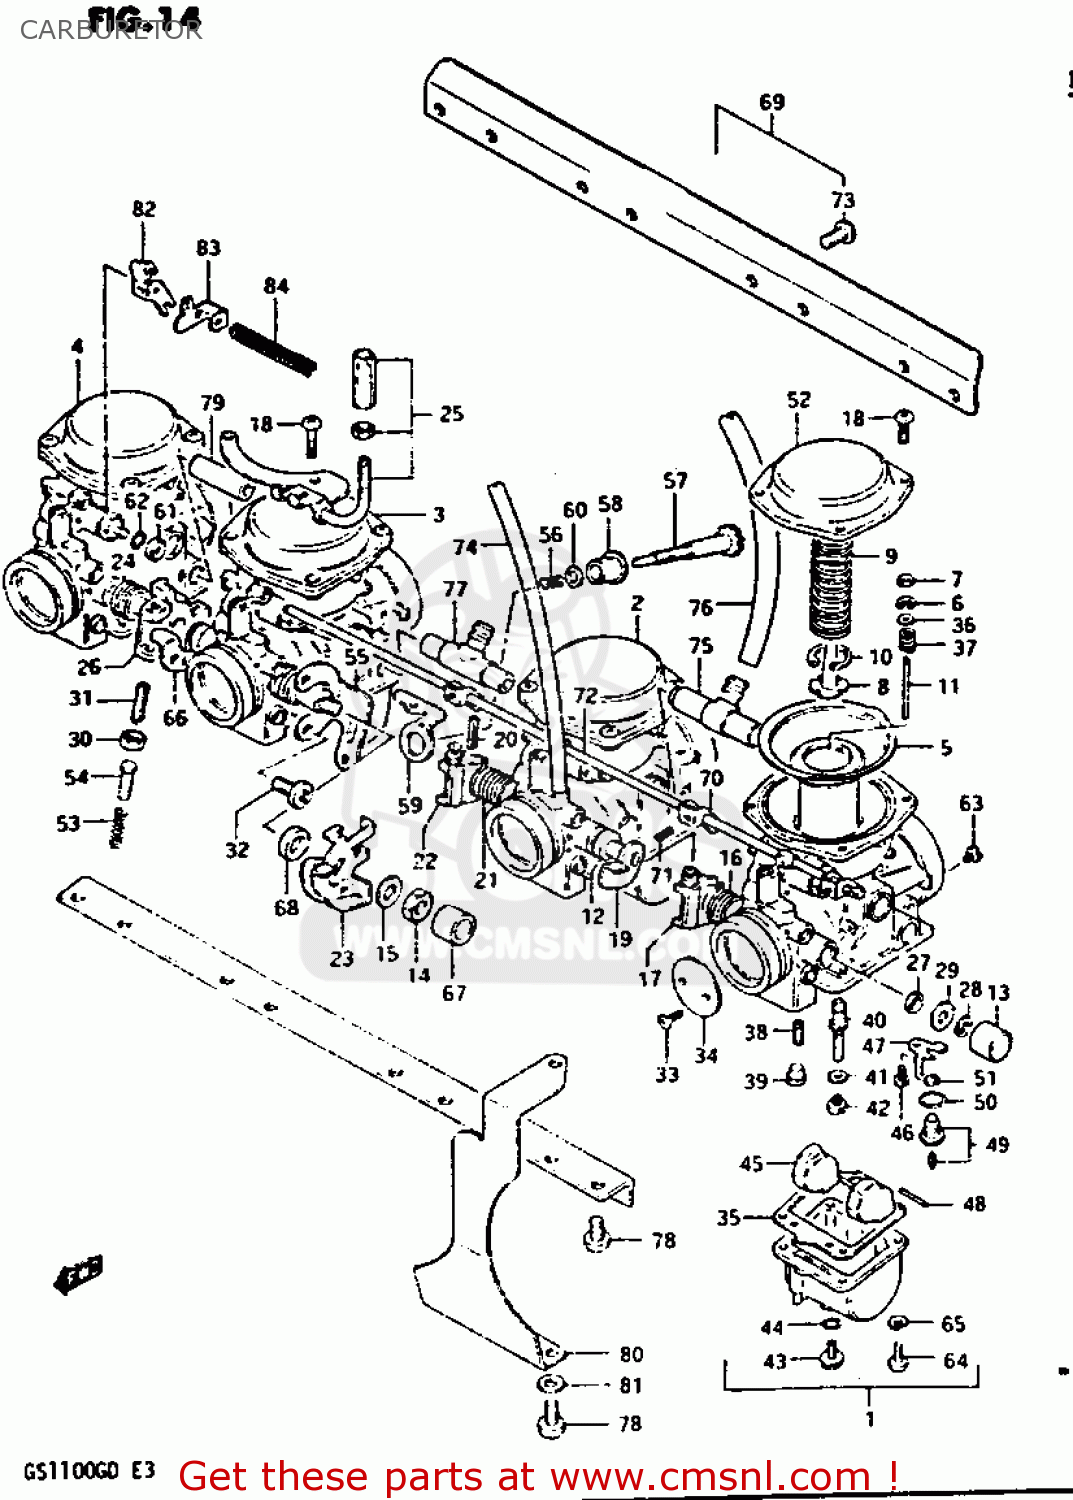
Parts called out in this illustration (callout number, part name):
1	CARBURETOR ASSEMBLY
2	CARBURETOR ASSEMBLY
3	CARBURETOR ASSEMBLY
4	CARBURETOR ASSEMBLY
5	DIAPHRAGM ASSY
6	CLIP,NEEDLE
7	RING
8	HOLDER,GUIDE
9	SPRING
10	E RING
11	NEEDLE,JET
12	GASKET
13	CAP
14	NUT
15	WASHER
16	SPRING,THROTTLE SHAFT
17	SHAFT,THROTTLE
18	SCREW
19	SHAFT,THROTTLE
20	PIN,THROTTLE SHAFT
21	SPRING,THROTTLE SHAFT
22	LEVER,THROTTLE SHAFT
23	LEVER ASSEMBLY,THROTTLE
24	SPRING,THROTTLE SHAFT
25	BRACKET,THROTTLE CABLE
26	SHAFT,THROTTLE
27	SEAL
28	E RING
29	GASKET,THROTTLE SHAFT (NAS)
30	NUT
31	SCREW
32	SCREW
33	SCREW
34	VALVE,THROTTLE
35	GASKET,FLOAT CHAMBER (NAS)
36	WASHER
37	SPRING
38	JET,PILOT
39	PLUG,NEEDLE JET
40	JET,NEEDLE
41	WASHER,NEEDLE NOZZLE
42	JET,MAIN(115)
43	PLUG,DRAIN
44	GASKET (NAS)
45	FLOAT
46	SCREW 4X6
47	PLATE,NEEDLE VALVE FITING
48	PIN,FLOAT
49	VALVE ASSY,NEEDLE
50	O-RING,NEEDLE VALVE
51	FILTER
52	COVER,DIAPHRAGM
53	SPRING,THROTTLE SCREW
54	PIN,THROTTLE LEVER
55	BRACKET,THROTTLE ADJUST
56	SPRING
57	SCREW
58	BUSH
59	BRACKET,THROTTLE ADJUST
60	WASHER
61	CAP,STARTER VALVE
62	O RING
63	JET,AIR
64	SCREW
65	LOCK WASHER
66	SHAFT,THROTTLE
67	RING
68	RING
69	CARBURETOR ASSEMBLY
70	LEVER
71	SCREW
72	SHAFT,STARTER
73	SCREW
74	HOSE
75	NIPPLE
76	HOSE,CARBURETOR
77	NIPPLE
78	SCREW
79	NIPPLE
80	CLAMP
81	WASHER
82	PLATE,CHOKE CABLE
83	LEVER,CHOKE CABLE
84	SPRING,CHOKE CABLE
